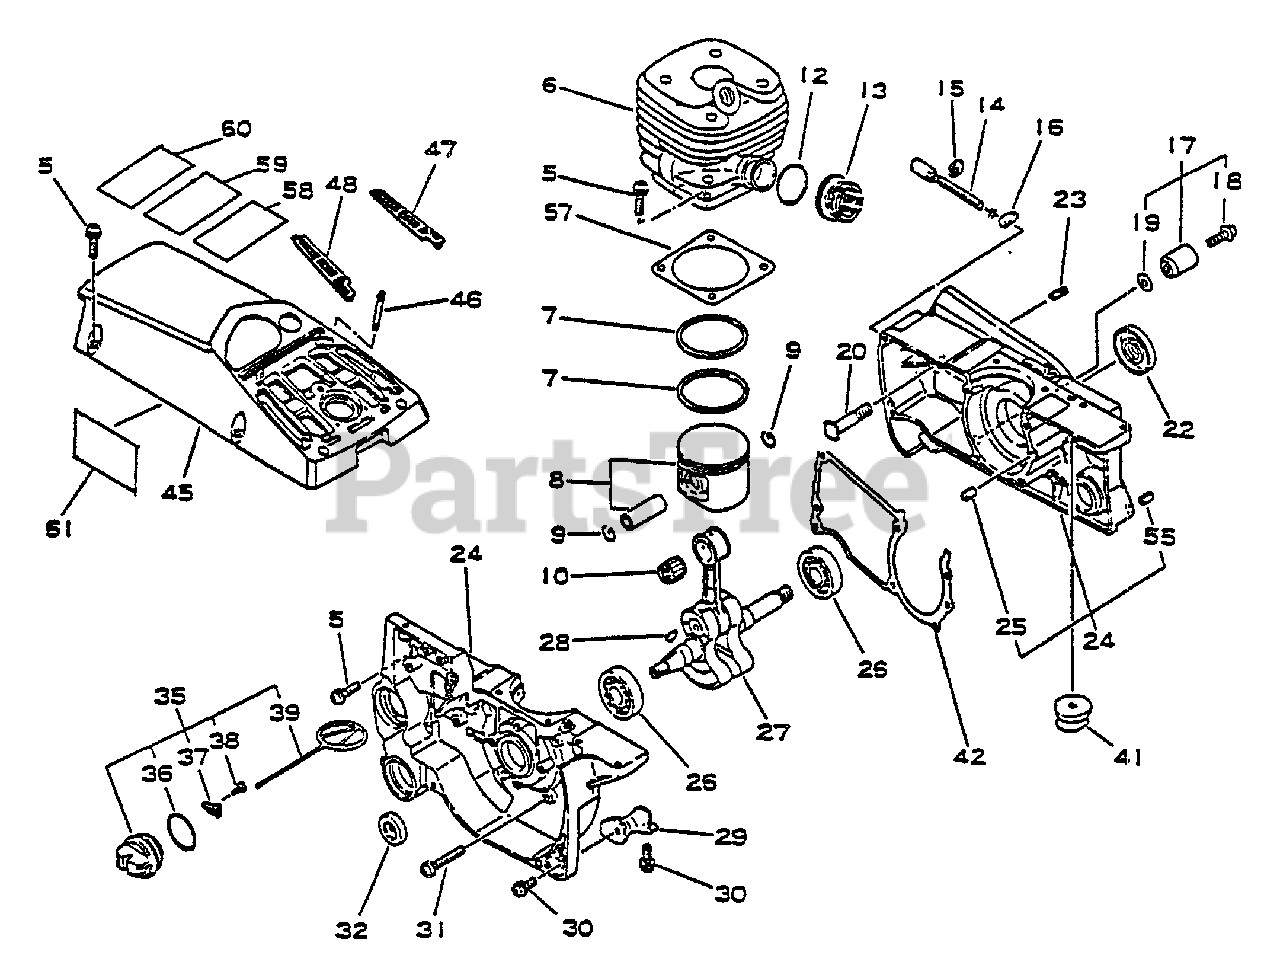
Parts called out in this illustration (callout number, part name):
5	BOLT 5×20
6	CYLINDER KIT
7	RING, PISTON
8	PISTON KIT
9	RING, SNAP
10	BEARING, NEEDLE
13	ADAPTOR, INTAKE
14	SCREW, ADJUSTER
16	TENSIONER, CHAIN
17	CHAIN CATCHER KIT
18	SCREW 5×20
19	WASHER, FLAT 5.5×10×0.8
20	STUD, GUIDE BAR 8
22	SEAL, OIL
23	VENT ASSY
24	CRANKCASE KIT
25	PIN, LOCATING 5×10
26	BEARING, BALL 6202
27	CRANKSHAFT
28	KEY, WOODRUFF
30	SCREW 5×14
31	BOLT M5×35
32	SEAL, OIL
35	CAP ASSY
37	RETAINER, CONNECTOR
38	SCREW, TAPPING 3×8
39	CONNECTOR, CAP L= 60 MM
42	GASKET, CRANKCASE
45	COVER, ENGINE
46	STUD
47	FILTER KIT
48	FILTER KIT
55	PIN, SPRING 5×10
57	GASKET, CYLINDER
58	LABEL - CAUTION
59	LABEL - CAUTION
60	LABEL, CAUTION
61	LABEL, EYE CATCHER
